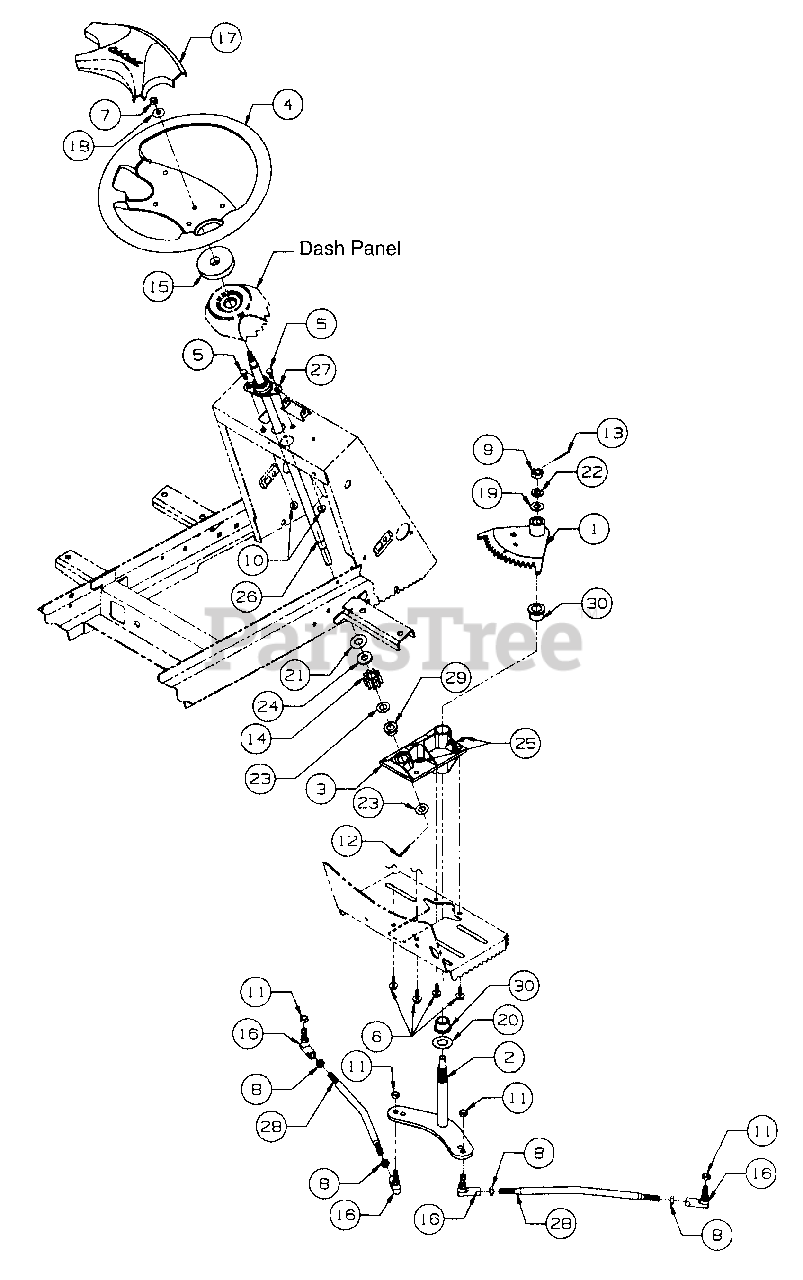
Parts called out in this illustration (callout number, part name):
1	Segment Assy, 18T - Steering
2	Arm Assy, Lower Steering
3	Housing Assy, Steering
4	Wheel, Steering
5	Screw, Hex Cap, 1/4-20 x .62, GR5
6	Screw, Hex Wash HD-TPTT, 5/16-18 x .75 Lg
7	Nut, Hex Center Lock, 5/16-24
8	Nut, Hex Jam, 3/8-24 GR5
9	Nut, Hex Slotted, 1/2-20 GR5
10	Nut, Hex Flange Lock, 1/4-20
11	Nut, Hex Lock, 3/8-24 GR5
12	Pin, Cotter, 1/8 Dia x 1
13	Pin, Cotter, 3/32 Dia x 1.25
14	Pinion, Steering
15	Gasket, Steering
16	Joint, Ball, 3/8-24
17	Insert, Steering Wheel
18	Washer, Bell, .340 x .88 x .06 Thk
19	Washer, Flat, .510 x 1 x .06 Thk
20	Washer, Flat, .760 x 1.5 x .03 Thk
21	Washer, Flat, .56 x 1 x .04 Thk
22	Washer, Lock, 1/2
23	Washer, Flat, .531 x 1 x .027 Thk
24	Washer, Rubber Flat, .50 x 1.12 x .125 Thk
25	Fitting, Lube, 3/16 Drive Type
26	Shaft, Steering
27	Bearing, Flange
29	Bearing, Flange, .503 ID
30	Bearing, Bronze Flange, .75 ID
